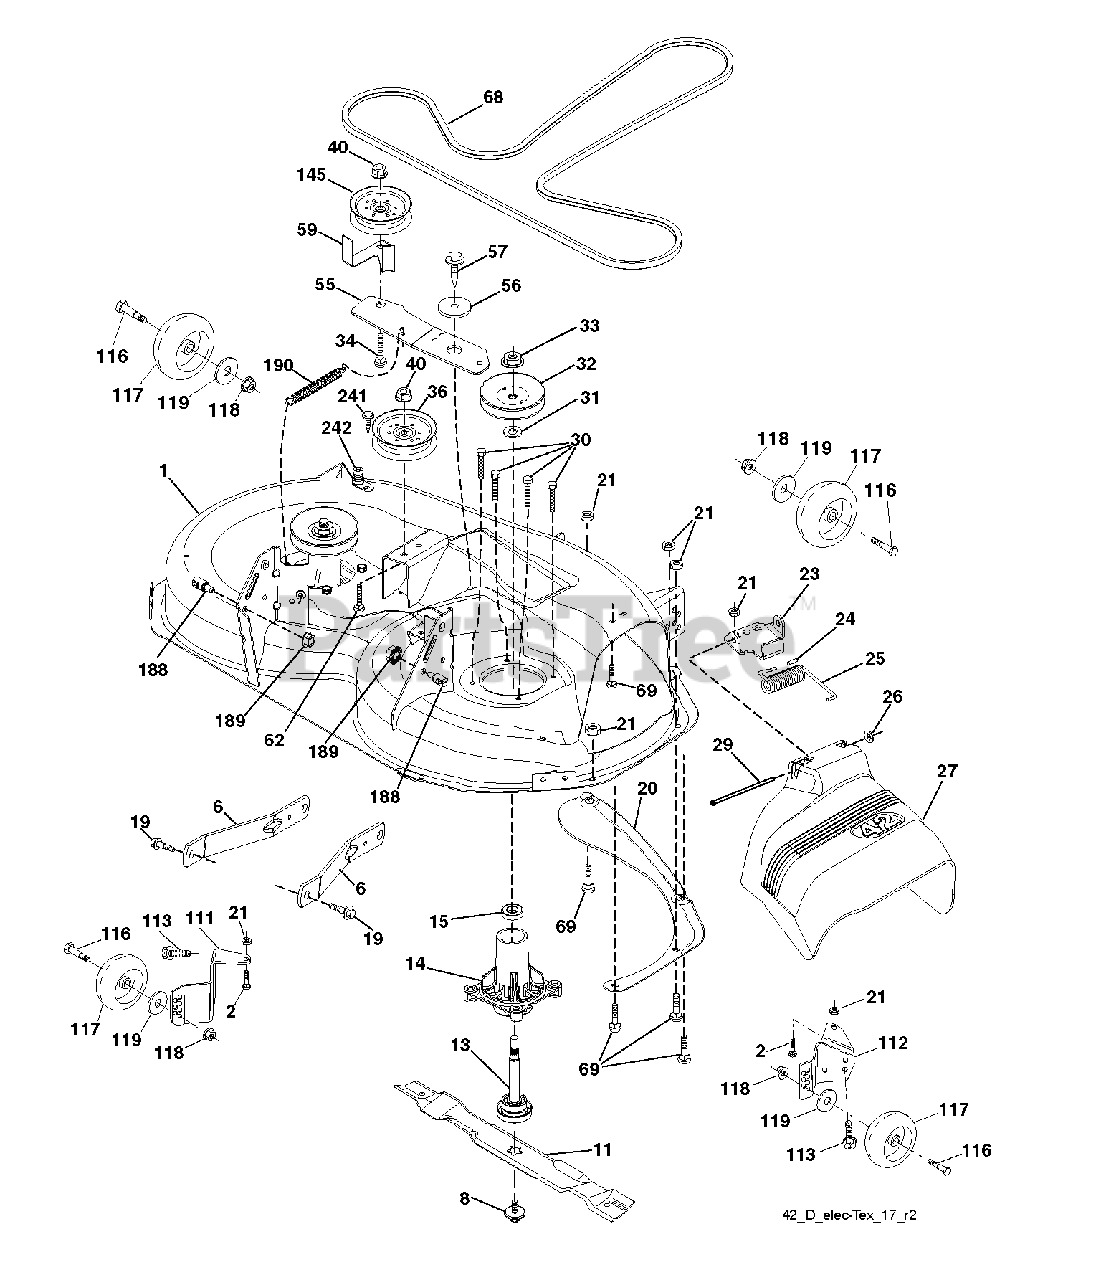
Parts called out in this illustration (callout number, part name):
1	DECK.WELDMENT.42"PNT.2GWB.668
6	ARM.SUSPENSION.MOWER.R
8	BOLT.WASHER.ASM.7/16-2
11	42" HI-LIFT BLADE
13	SHAFT.ASM.MDRL.N/GREASE.38
14	HOUSING MANDREL
15	BEARING
19	BOLT.SHOULDER
20	BAFFLE.VORTEX
23	BRKT.DEFLECTOR
24	CAP-SLEEVE LT
25	SPRING.TORSION.DEFLECT
26	NUT PUSH M
29	HINGE ROD
30	SCREW, WASHER HEAD
33	NUT.FLANGE.LOCK.TOP
55	IDLER.ARM
56	SPACER.RETAINER
57	SCREW 3/8-16X1
59	GUARD, BELT
69	BOLT
117	WHEEL GAGE.HALF.SPOKED
188	STUD.FASTNER.W/ANTI-ROTATE
189	NUT LOCK HEX FLANGE 5/16-18
190	SPRING.MOWER.DRIVE.ELECTRIC
242	PORT.WASHOUT
